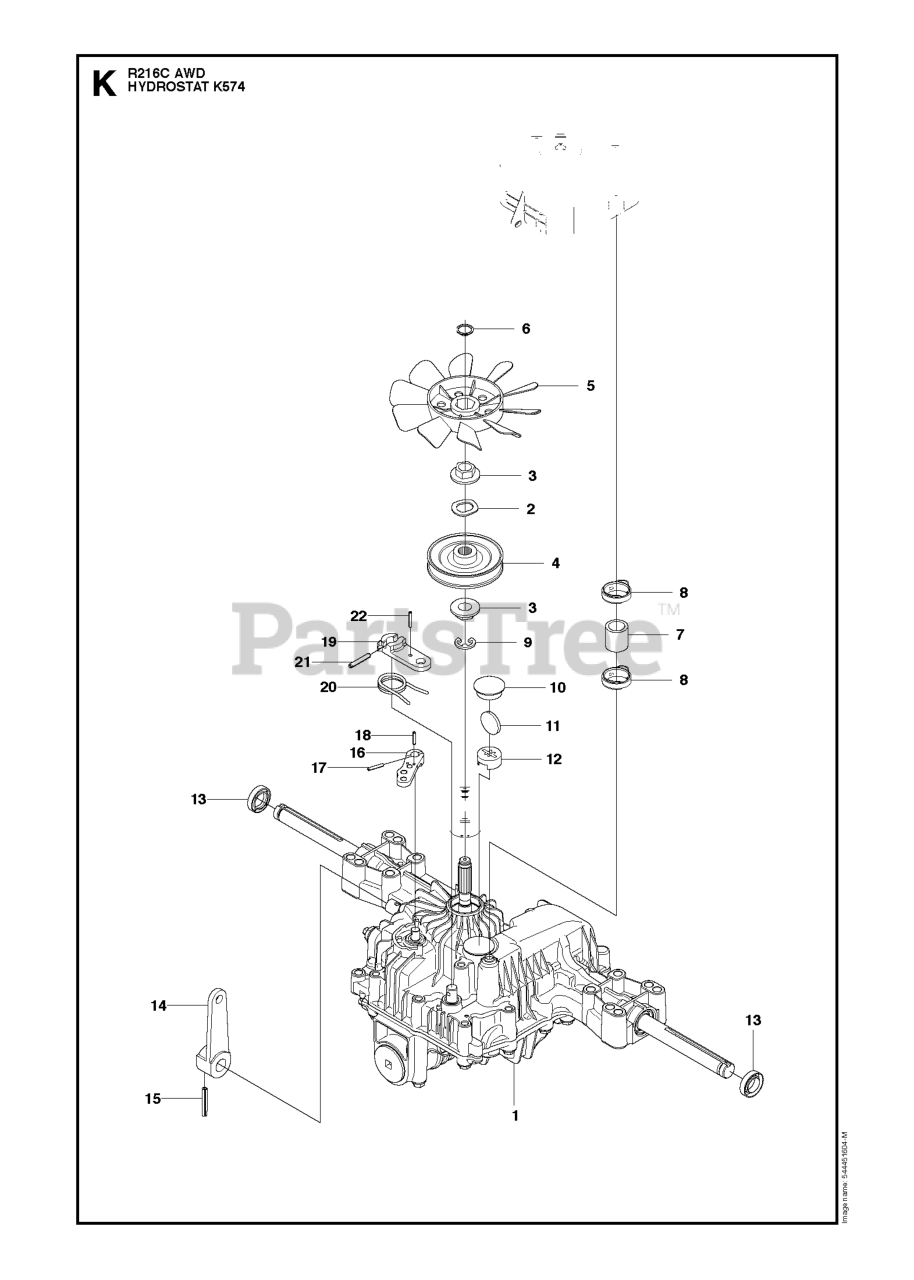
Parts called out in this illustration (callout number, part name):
1	HYDRAULMOTOR
5	FAN.BLACK.1A646083070
6	RETAINING RING **
8	CLAMP
12	MAGNET HOLDER
13	RP SEAL.19, 19216334280
14	CONTROL LEVER
20	RETURN SPRING
